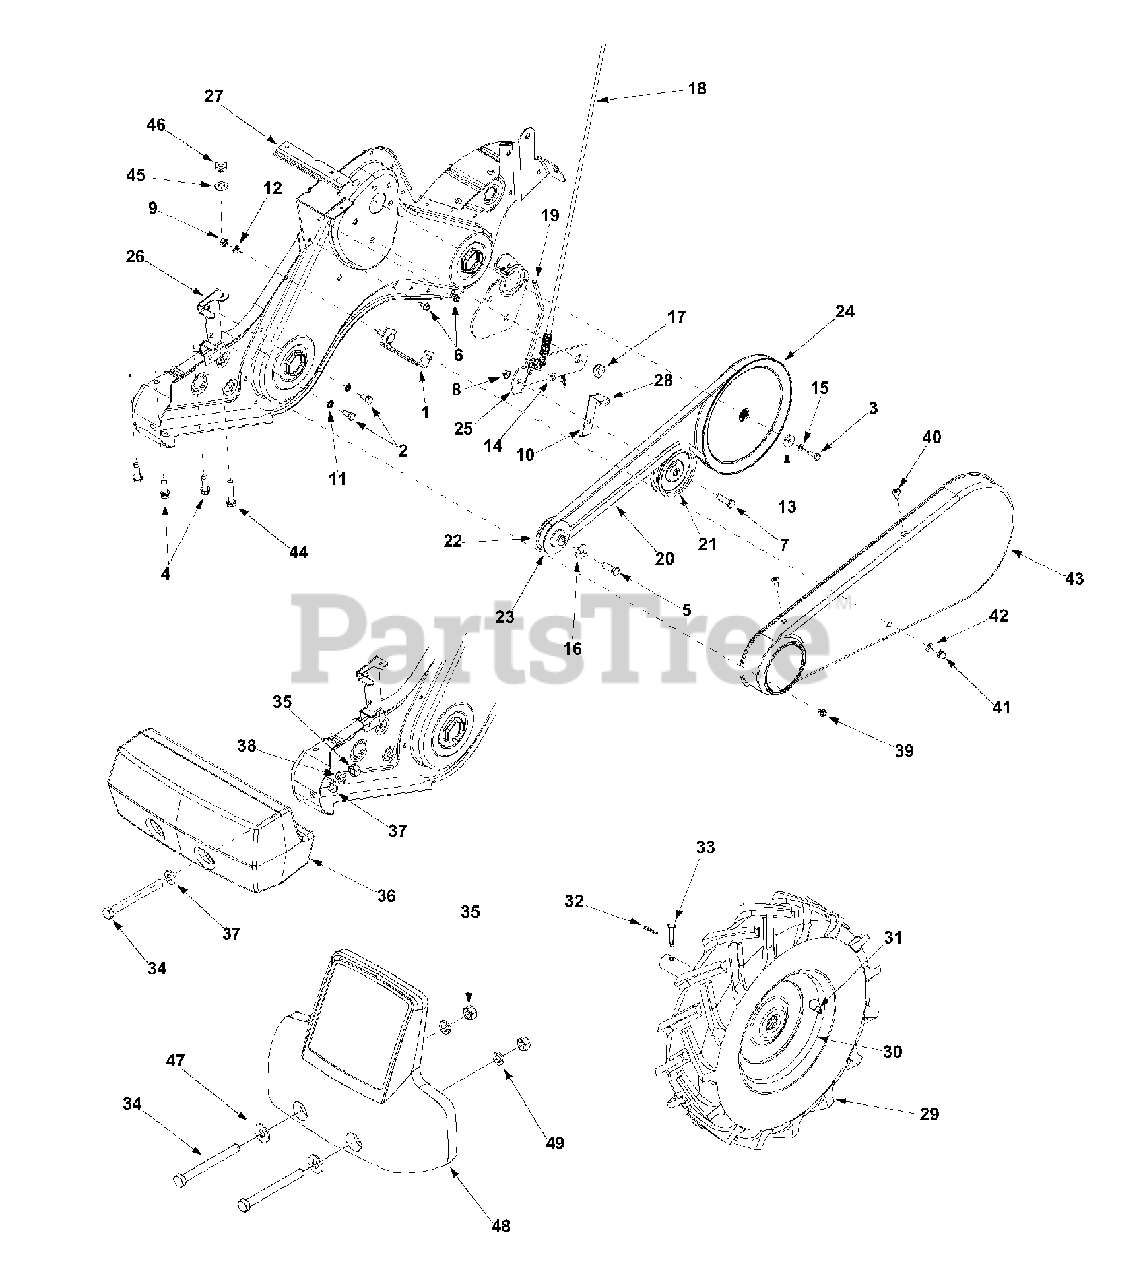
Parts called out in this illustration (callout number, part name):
2	Hex Bolt 5/16-24 x .62"
3	Hex Bolt 1/4-28 x .75"
4	Hex Washer Screw 3/8-16 x 1.25"
5	Hex Bolt 3/8-24 x 1.0
6	Hex Washer Screw
7	Hex Cap Screw 3/8-16 x 1.25
8	Lock Jam Nut 3/8-16
9	Hex Nut 5/16-18
10	Internal Cotter Pin
11	Hairpin Clip
12	Lock Washer 5/16"
13	Flat Washer .25 ID x .93 OD
14	Spring Washer .317 ID x .625 OD
15	Lock Washer 1/4" ID
16	Bell Washer .396 ID x 1.14 OD
17	Shoulder Nut 7/16-20
18	Clutch Cable
19	Idler Pulley Rod
20	V-Belt
21	Flat Idler w/Flange 3.75 OD
22	Outer Engine Pulley Half
23	Inner Engine Pulley Half
24	Input Pulley
25	Idler Bracket
26	Belt Keeper Bracket
32	Clevis Pin
33	Internal Cotter Pin
34	Hex Bolt 1/2-13 x 5.0
35	Hex Nut 1/2-13
36	Counterweight
37	Flat Washer .510 ID x 1.0 OD
38	Lock Washer 1/2
39	Hex Screw 1/4-20 x .375
40	Screw 1/4-14 x .625
41	Lock Nut
42	Flat Washer .250 ID x .620 OD
44	Hex Bolt 5/16-18 x 1.5
45	Bell Washer .340 ID x .872 OD
46	Hex Nut 5/16-18
47	Flat Washer .50 ID x 1.25 OD
48	Counterweight
49	Lock Washer .50
